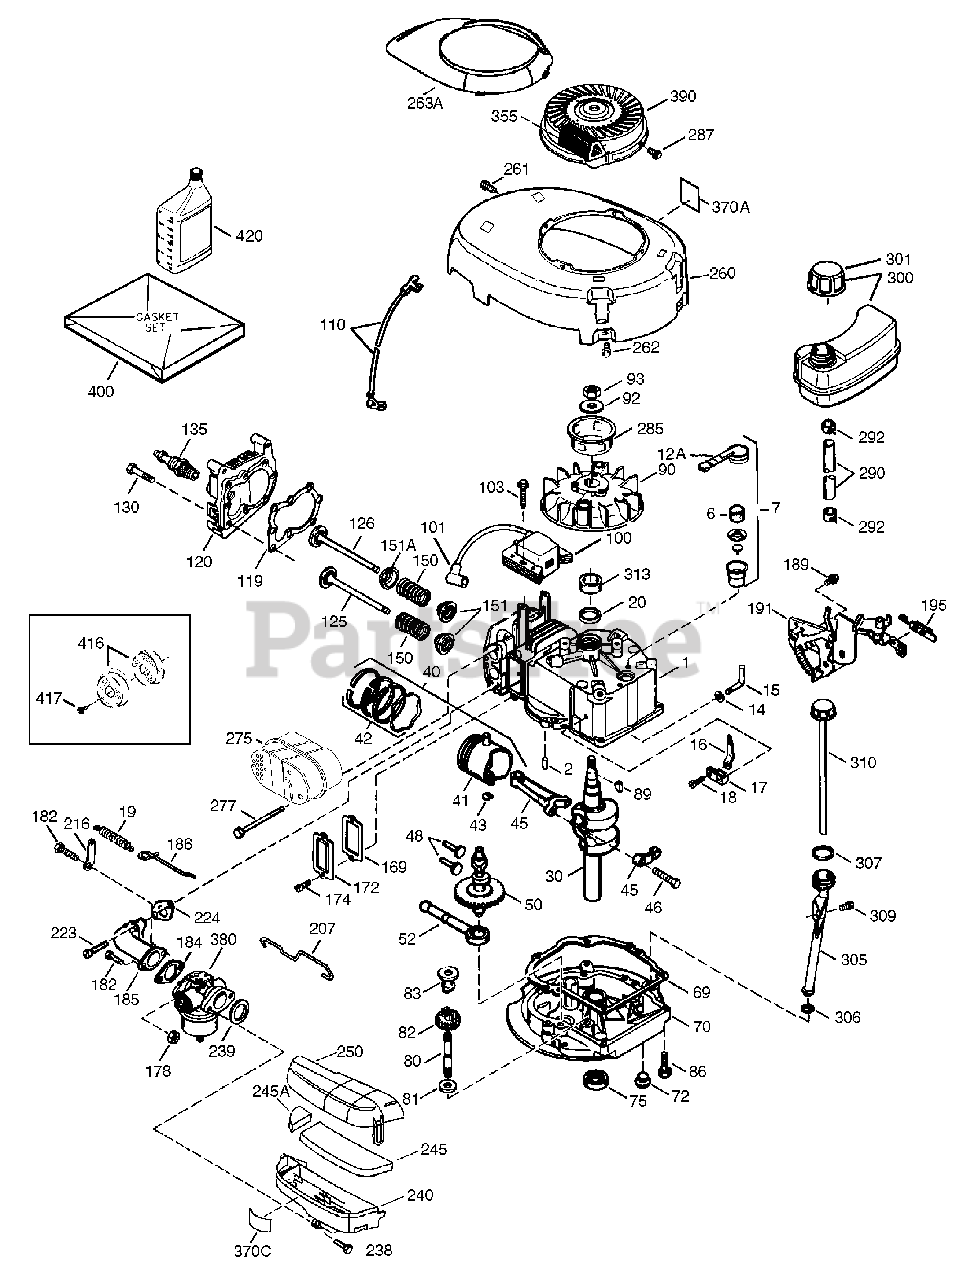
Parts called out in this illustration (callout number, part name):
1	Cylinder (Incl. 2, 20 & 150)
2	Dowel Pin
6	Breather Element
7	Breather Body ASM (Incl. 6 & 12A)
12A	Breather Cover & Tube
14	Washer
15	Governor Rod (Incl. 14)
16	Governor Lever
17	Governor Lever Clamp
18	Screw, Torx T-15
19	Extension Spring
20	Oil Seal
30	Crankshaft
40	Piston, Pin & Ring Set (Std.)
40	Piston, Pin & Ring Set (.010" OS)
40	Piston, Pin & Ring Set (.020" OS)
41	Piston & Pin ASM (Std.)(Incl. 43)
41	Piston & Pin ASM (.010" OS)(Incl. 43)
41	Piston & Pin ASM (.020" OS)(Incl. 43)
42	Ring Set (Std.)
42	Ring Set (.010" OS)
42	Ring Set (.020" OS)
43	Piston Pin Retaining Ring
45	Connecting Rod ASM (Incl. 46)
46	Connecting Rod Bolt
48	Valve Lifter
50	Camshaft (NCR)
52	Oil Pump ASM
69	Mounting Flange Gasket
70	Mounting Flange (Incl. 72 thru 83, 306)
72	Oil Drain Plug
75	Oil Seal
80	Governor Shaft
81	Washer
82	Governor Gear ASM (Incl. 81)
83	Governor Spool
86	Screw
89	Flywheel Key
90	Flywheel
92	Belleville Washer
93	Flywheel Nut
100	Solid State Ignition
101	Spark Plug Cover
103	Screw, Torx T-15
110	Ground Wire
119	Cylinder Head Gasket
120	Cylinder Head
125	Exhaust Valve (Std.)(Incl. 151)
126	Intake Valve (Std.)(Incl. 151)
130	Screw
135	Resistor Spark Plug (RJ19LM)
150	Valve Spring
151	Valve Spring Cap
151A	Intake Valve Seal
169	Valve Cover Gasket
172	Valve Cover
174	Screw
178	Nut & Lock Washer
182	Screw
184	Carburetor To Intake Pipe Gasket
185	Intake Pipe
186	Governor Link
189	Screw
191	S.E. Brake Bracket (Incl. 195)
195	Terminal
207	Throttle Link
216	R.P.M. Adjusting Lever
223	Screw
224	Intake Pipe Gasket
238	Screw
239	Air Cleaner Gasket
240	Air Cleaner Body
245	Air Cleaner Filter
245A	Air Cleaner Filter
250	Air Cleaner Cover
260	Blower Housing
261	Screw
262	Screw
263A	Starter Grill
275	Muffler
277	Screw
285	Starter Cup
287	Screw
290	Fuel Line
292	Fuel Line Clamp
300	Fuel Tank (Incl. 292 & 301)
301	Fuel Cap
305	Oil Fill Tube
306	"O"-Ring
307	"O"-Ring
309	Screw
310	Dipstick
313	Spacer
355	Starter Handle
370A	Lubrication Decal
370C	Primer Decal (3X)
380	Carburetor (Incl. 184)
390	Rewind Starter
400	Gasket Set
416	Spark Arrestor Kit
417	Screw
420	SAE30 4-Cycle Engine Oil (Quart)
